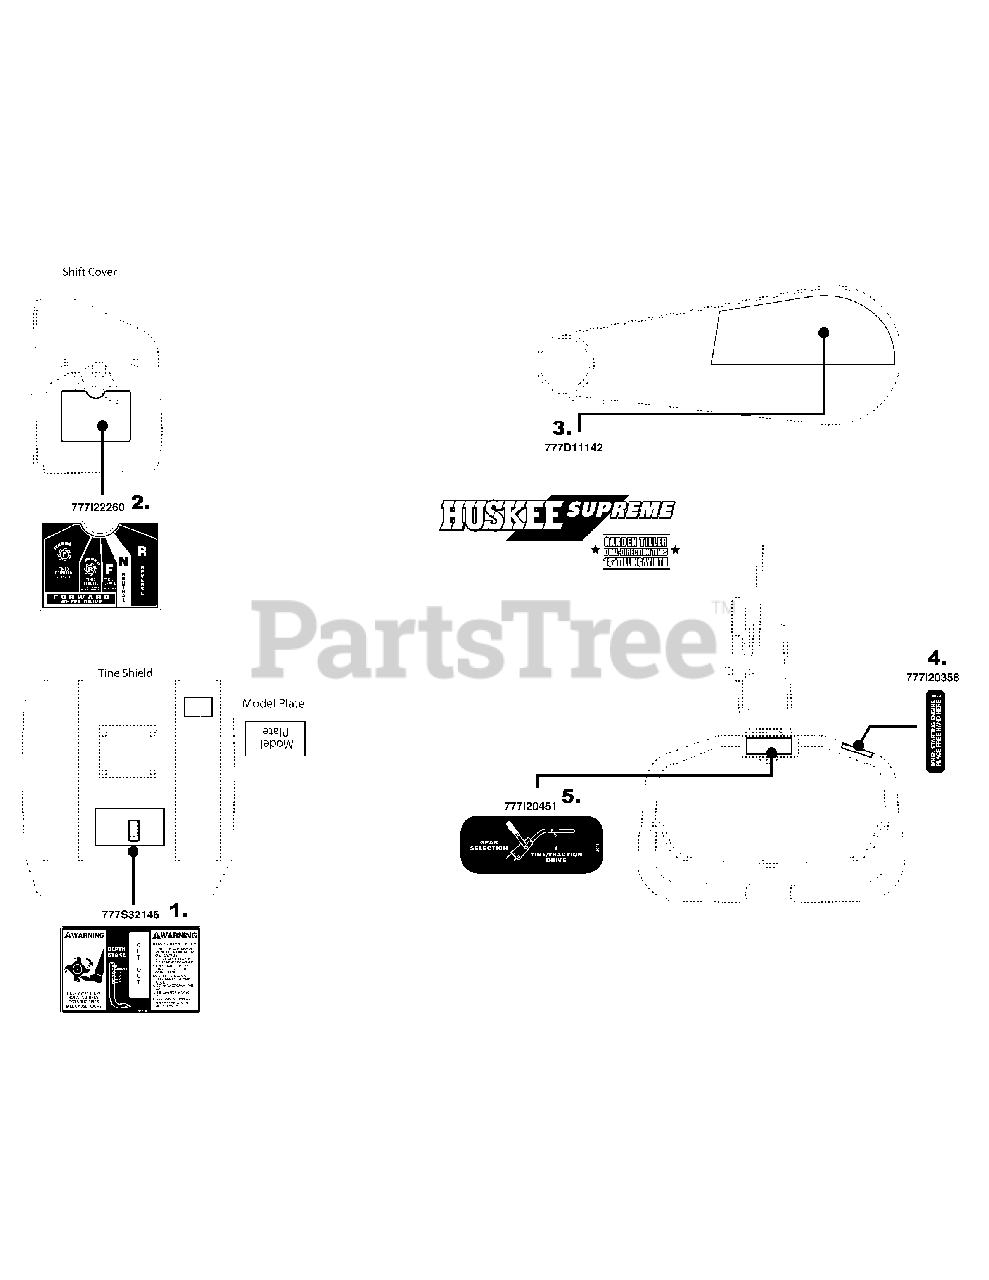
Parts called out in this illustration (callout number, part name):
1	LABEL-TINE SHIELD
2	LABEL-SHIFT P0SITION
3	LABEL-TILLER BELT COVER HUSKEE
4	LABEL-PLACE HAND HERE
5	LABEL-GEAR/TRACTIO
